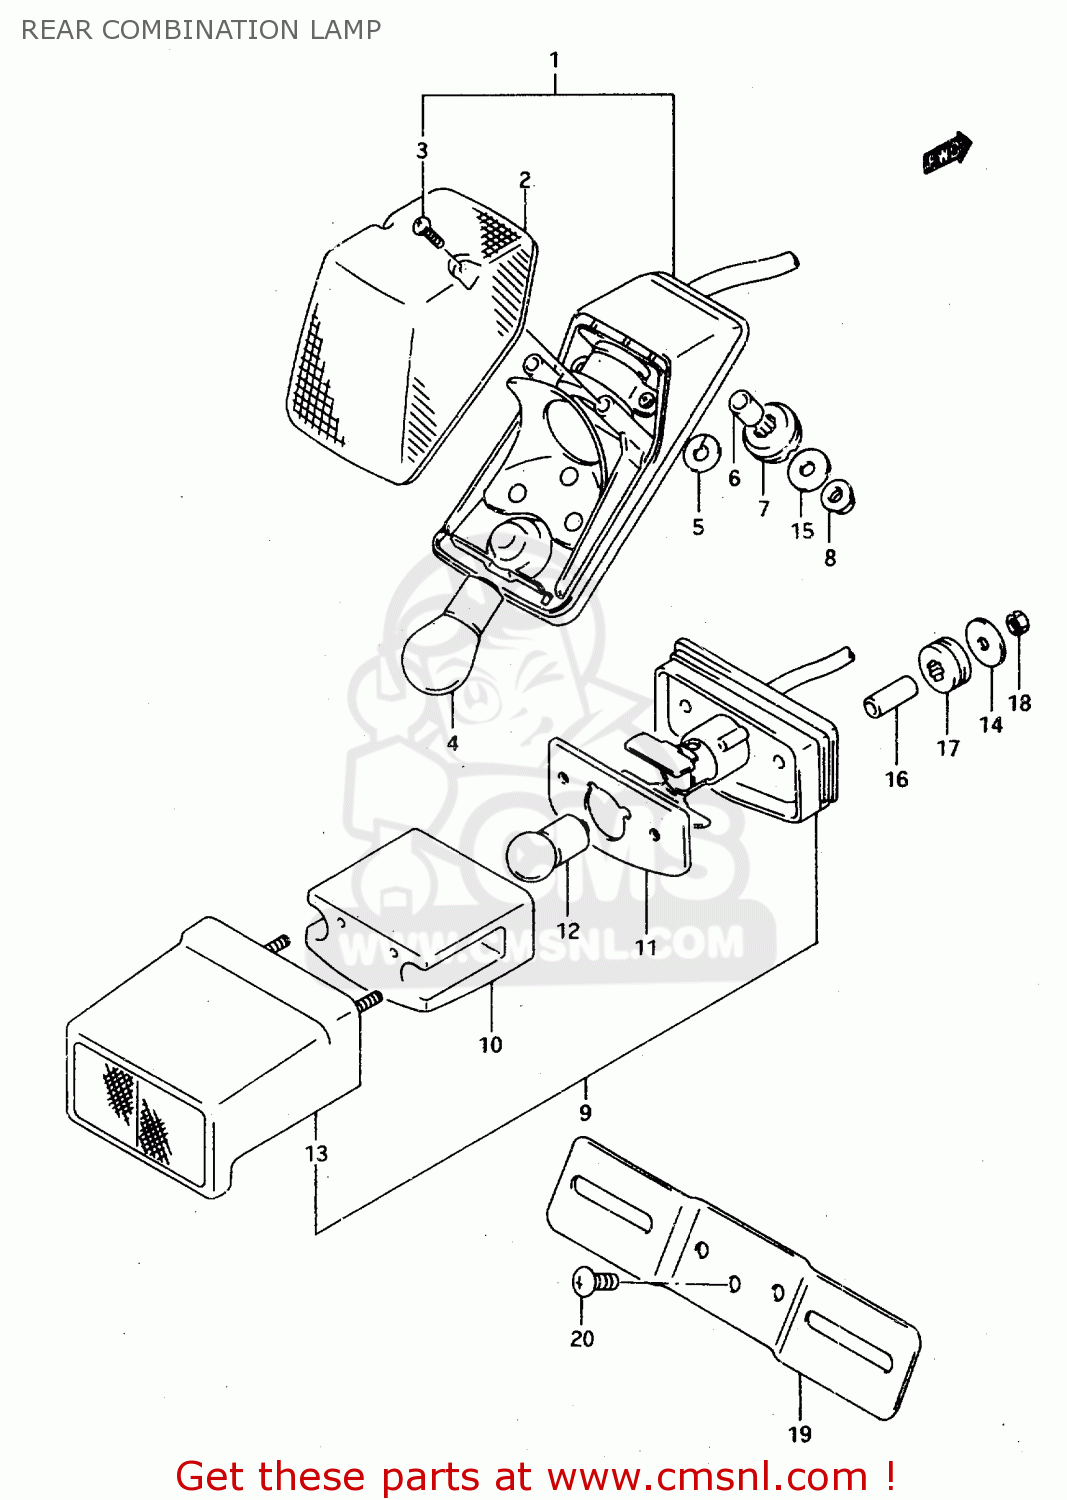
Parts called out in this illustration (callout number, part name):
1	LAMP ASSY, REAR COMBINATION
2	LENS
3	SCREW
4	BULB(12V21/5W)
5	GASKET (NAS)
6	SPACER(6.4X9.2X12)
7	CUSHION
8	NUT
9	LAMP ASSY,LICENSE
10	LENS
11	GASKET,LICENSE LAMP (NAS)
12	BULB
13	REFLEX REFLECTOR & COVER
14	WASHER(4.3X20X1.4)
15	WASHER(6.5X20X1.6)
16	SPACER (4.3X9X23.5)
17	CUSHION
18	NUT
19	PLATE,RR LICENSE
20	SCREW
